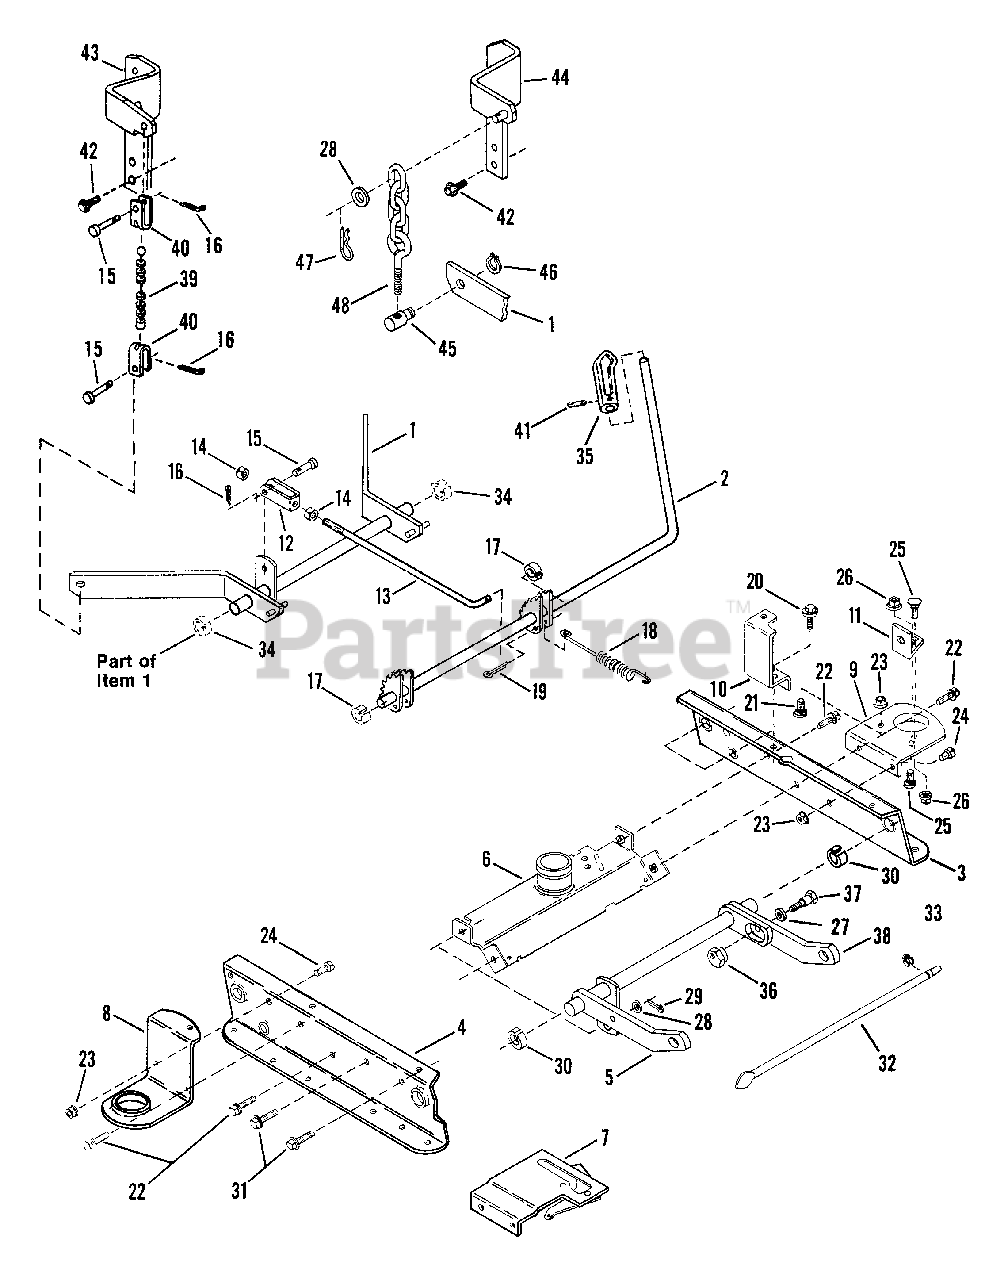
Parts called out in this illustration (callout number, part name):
1	ASSEMBLY, Rear Lift Arm
2	LEVER, Height Adjustment Lift
3	RAIL, Left Half
4	RAIL, Right Half
5	STRUCTURE, Front Lift Arm
6	BRACE, Weldment
7	ASSEMBLY, Clutch Plate
8	SPINDLE, Brace (Right)
9	SPINDLE, Brace (Left)
10	BRACKET, Cover
11	ANCHOR
12	CLEVIS,Timing Rod
13	ROD, Timing
14	NUT, 3/8-24 Hex
15	PIN, 3/8 x 1 1/16" Clevis
16	PIN, 3/32 x 3/4" Cotter
17	RING, Black
18	SPRING, Cam Lift
19	PIN, 5/32 x 1" Cotter
20	SCREW, 1/4-20 x 5/8" Self-Tapping
21	SCREW, 3/8-24 x 1" Hex Head Cap
22	SCREW, 3/8-16 x 1" Self-Tapping
23	NUT, 3/8-24 Hex Lock
24	SCREW, 3/8-24 x 3/4" Hex Head Cap
25	BOLT, 5/16-18 x 3/4" Carriage
26	NUT, 5/16-18 Hex Flange Lock
27	WASHER, 3/8 Internal Tooth Lock
28	WASHER, 3/8" Flat
29	PIN, 1/8 x 3/4" Cotter
30	RING, Red
31	SCREW, 5/16-18 x 5/8" Self-Tapping
32	SUPPORT, Rod
33	RING, Retaining
34	RING, Blue
35	GRIP, Height Adjustment Lever
36	ECCENTRIC, Leveling
37	BOLT, 3/8-24 x 3/4" Shoulder
38	ARM, Front Lift (Left Side)
39	CABLE, 42" Deck 3.75"
40	BRACKET, Cable
41	PIN, 3/16 x 3/4" Roll
42	SCREW, 5/16-18 x 1" Self-Tapping
43	DECK-WING, Rear (Right)
44	DECK-WING, Rear (Right)
46	RING, 5/8" External Retaining
47	PIN, 3/32 x 1-3/16 Cotter Hair
48	ASSEMBLY, Bolt & Chain Adjuster
